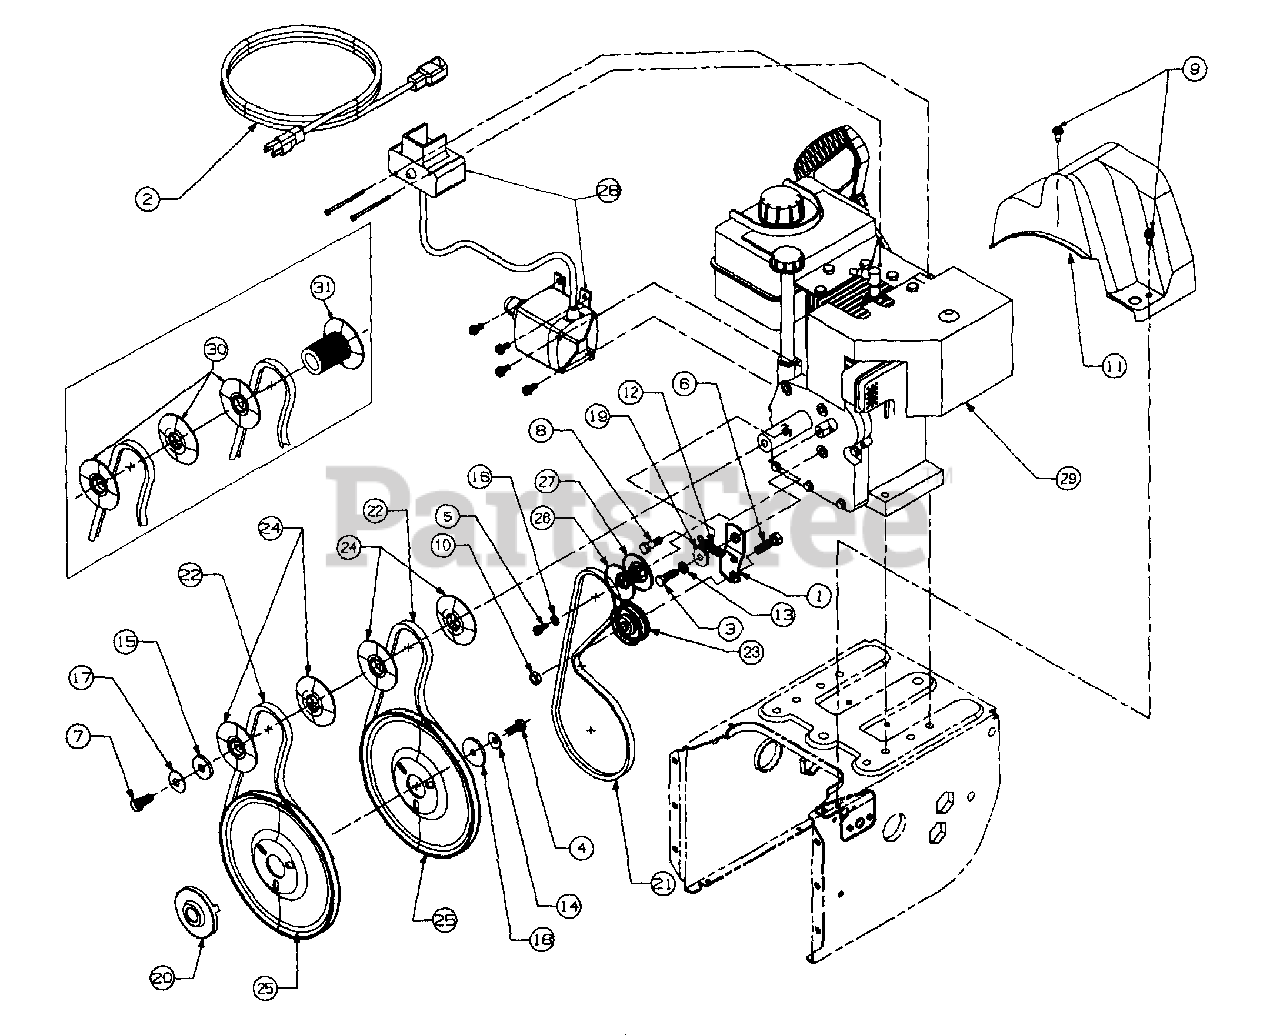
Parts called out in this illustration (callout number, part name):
3	Screw
6	Screw
11	Belt Cover
12	Spring
13	Washer - Flat
14	Washer - Bell
15	Washer - Flat
16	Washer - Lock
17	Washer - Bell
18	Washer - Flat
19	Shoulder Spacer
20	Pulley, Adapter
21	V-Belt
22	V-Belt Matched
23	Idler, Flat
24	Pulley, Half
25	Pulley - Auger
26	Pulley Half
27	Pulley Half
28	Starter (724E)
29	Engine
30	Pulley, Half (724E)
31	Pulley, Half (724E)
